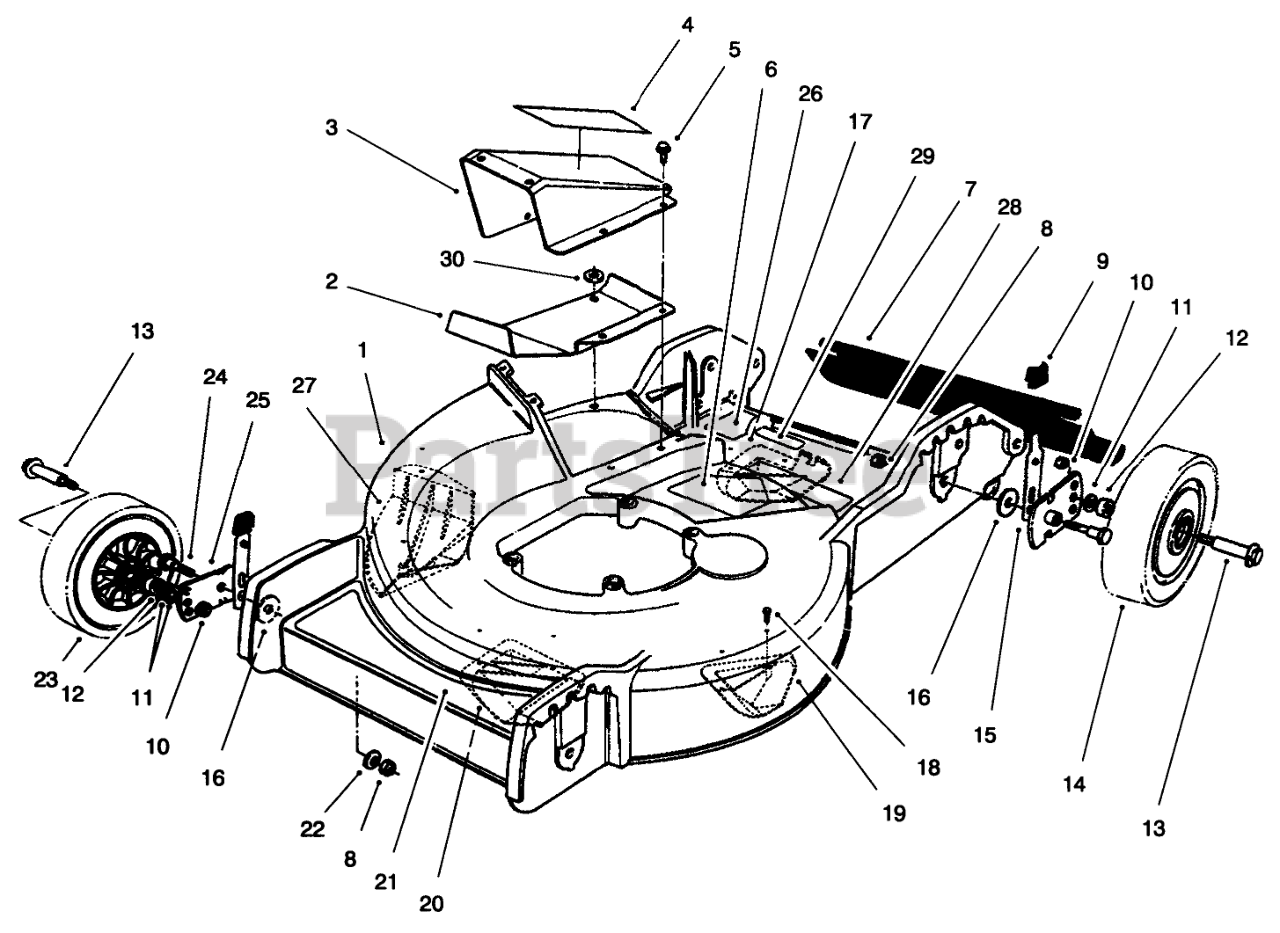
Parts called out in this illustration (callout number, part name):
1	Housing-18- (Incl. Ref. #6,17-20, & 27-29)
2	DISCHARGE KICKER
3	Cover-Discharge (Incl. Ref. #4)
4	DECAL - COVER
5	SCREW
6	DECAL-DANGER
7	SHIELD - TRAILING
8	NUT-LOCK, NI
9	KNOB-ARM
10	NUT-HEX
11	WASHER
12	WHEEL SPACER
13	BOLT-WHEEL
14	8" WHL & TIRE ASM
15	SPRING ARM ASM
16	PIVOT WASHER
17	KICKER
18	SCREW-PPH
19	KICKER
20	KICKER
21	DECAL - DECK
22	WASHER-BELLEVILLE
23	7" WHL & TIRE ASM
24	5/16-18 PIVOT SCREW
25	PIVOT ARM ASSY
26	DECAL - DANGER
27	KICKER
28	DECAL-INSTRUCTION, SAFETY
29	DECAL-WARNING
30	WASHER-FLAT
